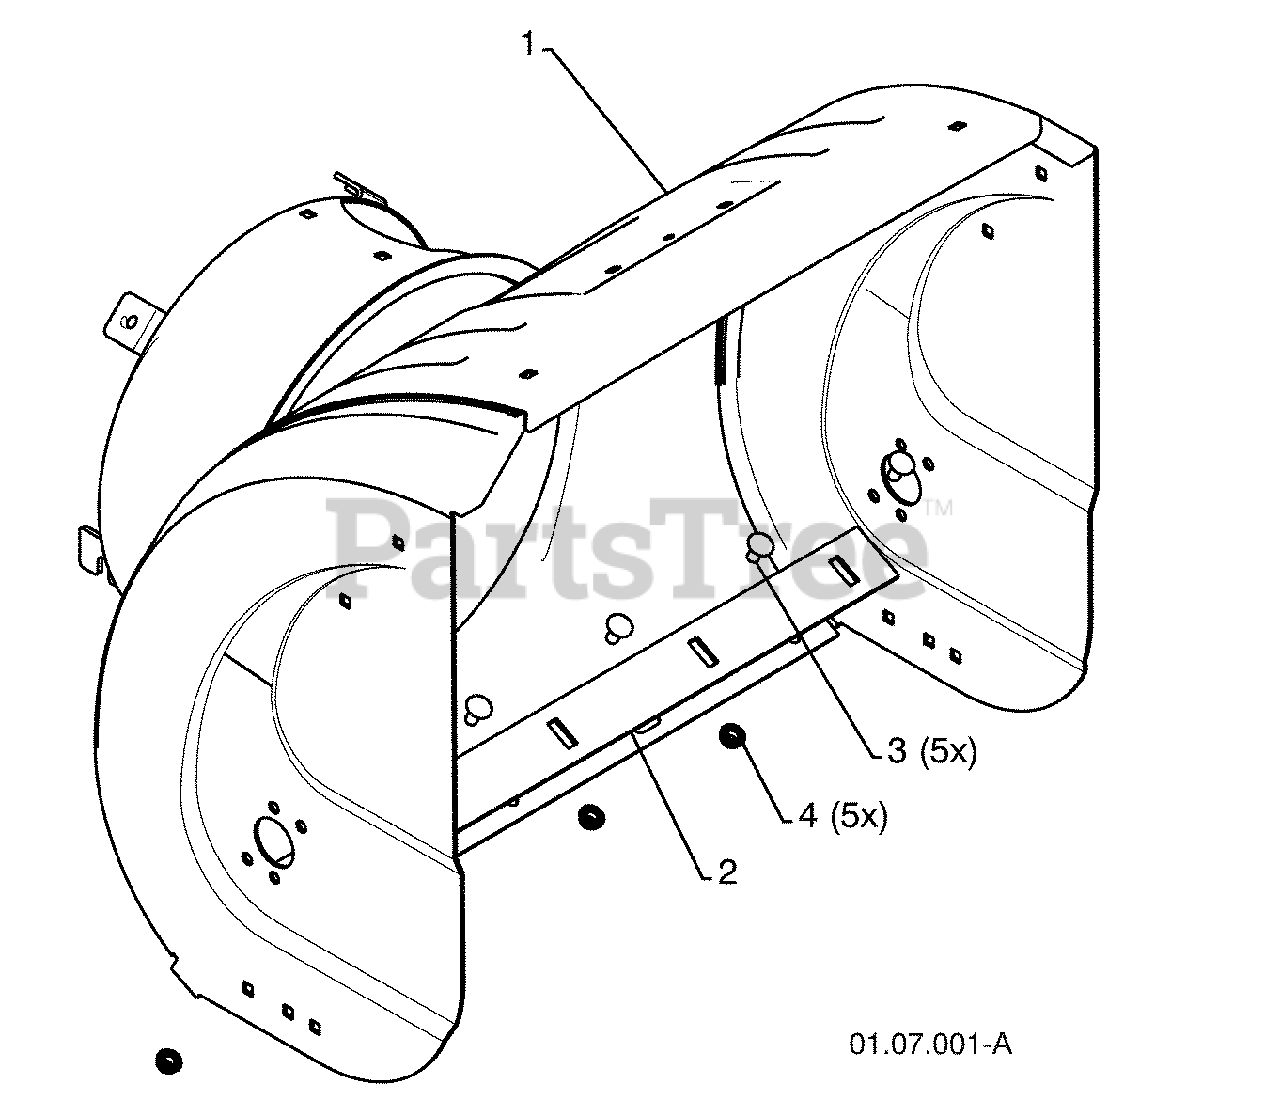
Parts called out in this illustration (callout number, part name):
1	AUGER HOUSING
2	SCRAPPER BAR
3	CARRIAGE BOLT 5/16-18 X .625
4	NUT 5/16-18
